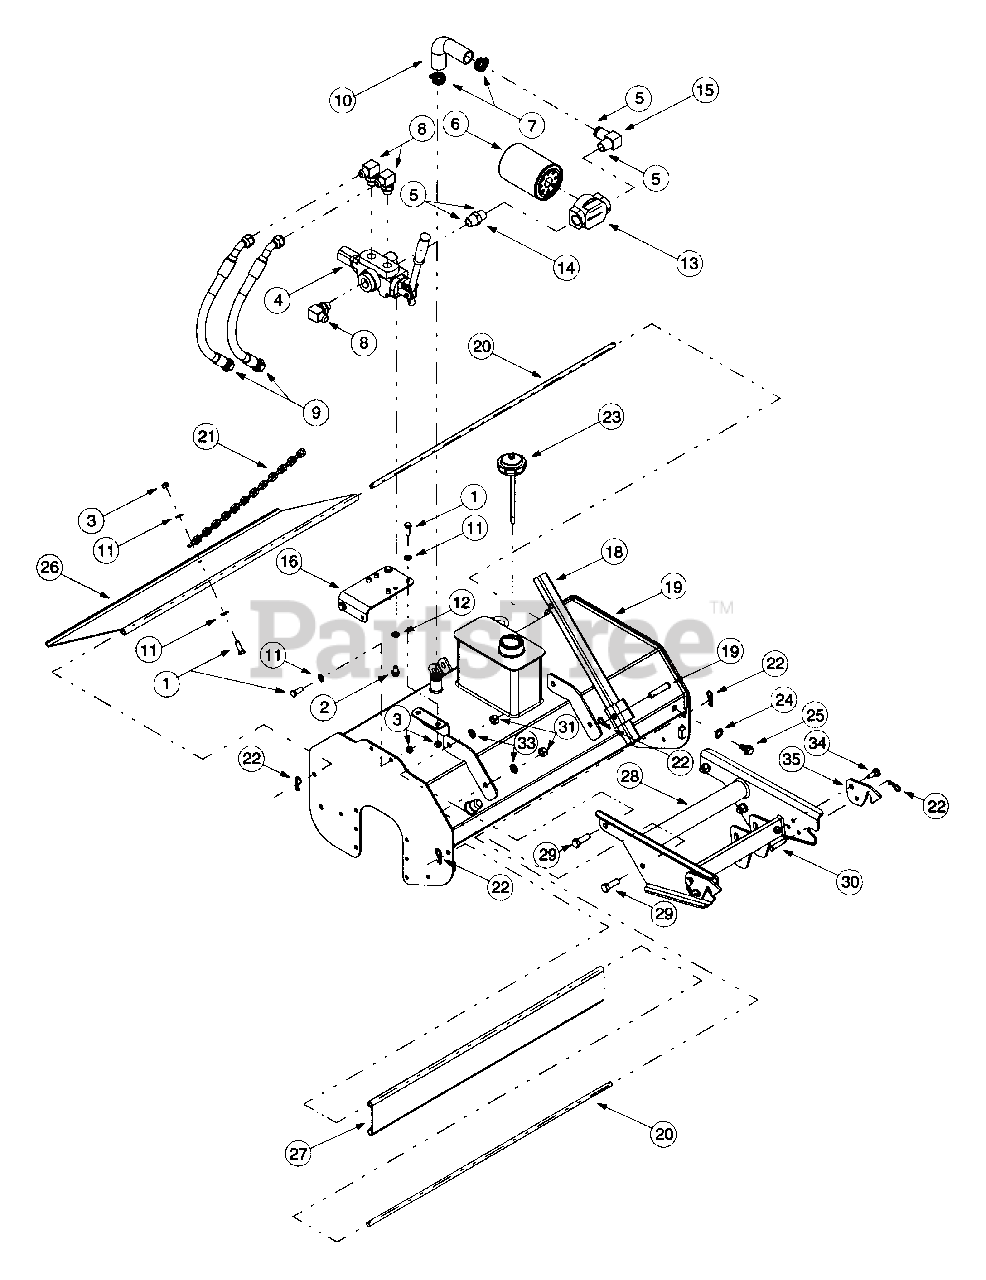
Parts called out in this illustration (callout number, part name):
1	Hex Cap Screw, 3/8-16 x 1.0
2	Shoulder Screw, 3/8-16 x .625
3	Hex Lock Nut, 3/8-16
4	Energy Hydraulic Valve
5	Locktite Hydraulic Sealant
6	Oil Filter
7	Adjustable Hose Clamp
8	90° Hydraulic Adapter, 7/8
9	Hydraulic Hose, 7/8-14
10	90° Hydraulic Hose, 1.37 x 1.0
11	Flat Washer, .375 x .738 x .063
12	Lock Washer, 3/8
13	Filter Housing
14	Hydraulic Adapter, 3/4 x 3/4
15	90° Hydraulic Adapter, 3/4 x 1.0
16	Valve Mounting Bracket
19	Clevis Pin, .50 x 2.0
20	Shield Pivot Rod
21	Chain, 24.37"
22	Internal Cotter Pin
23	Vented Tank Cap
24	Stat-O-Seal O Ring
25	Drain Plug
26	Rear Tine Shield, 30"
27	Front Tine Shield, 30"
28	Sleeve Hitch Assembly
29	Hex Cap Screw, 1/2-13 x 1.5
30	Clevis Pin, 3/8 x 1.75
31	Hex Nut, 1/2-13
33	Lock Washer, 1/2
34	Shoulder Screw, .50 x .27, 3/8-16
